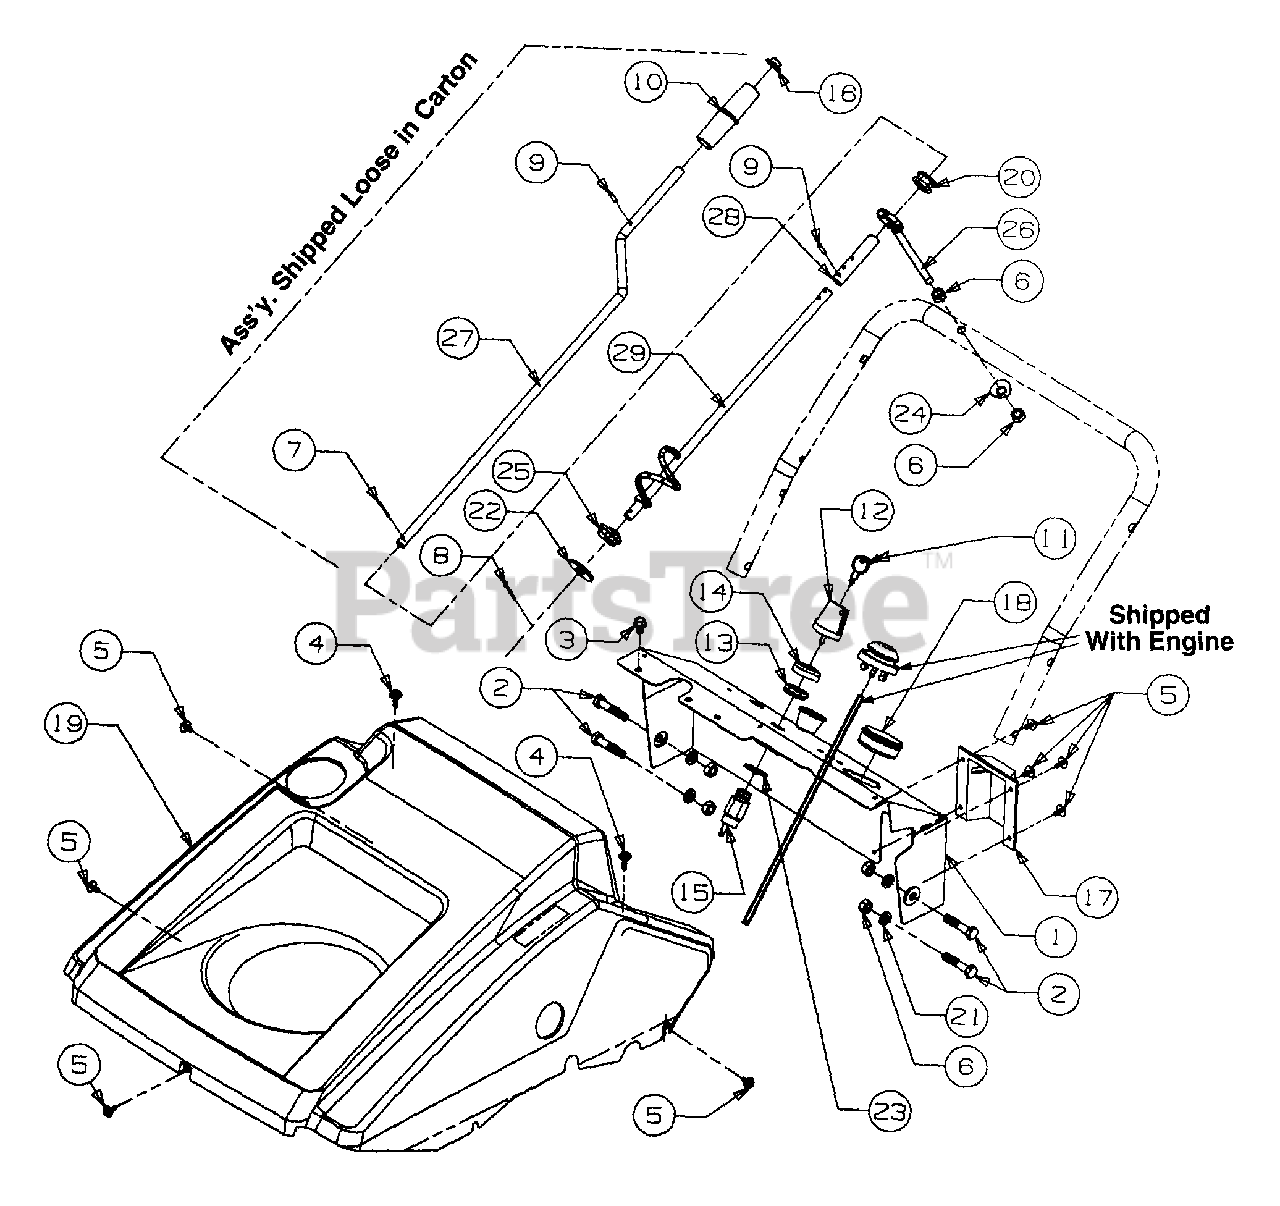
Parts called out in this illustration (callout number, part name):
1	Dash
2	Screw - Hex Cap
4	Screw - Hex
6	Nut - Hex
7	Pin - Cotter
8	Pin - Cotter
9	Pin Roll
10	Knob - Chute Crank
11	Key - Ignition
12	Key - Ignition with Logo
13	Nut - Ignition Switch
14	Cover - Ignition Switch
15	Switch
17	Cover - Choke
18	Plug - Insert
19	Shroud - Gray
20	Grommet - Rubber
21	Washer - Lock
22	Washer - Flat
23	Washer - Lock Internal
24	Washer - Saddle
25	Bushing - Hex
26	Eyebolt - Chute Crank
28	Spacer
29	Crank - Lower
